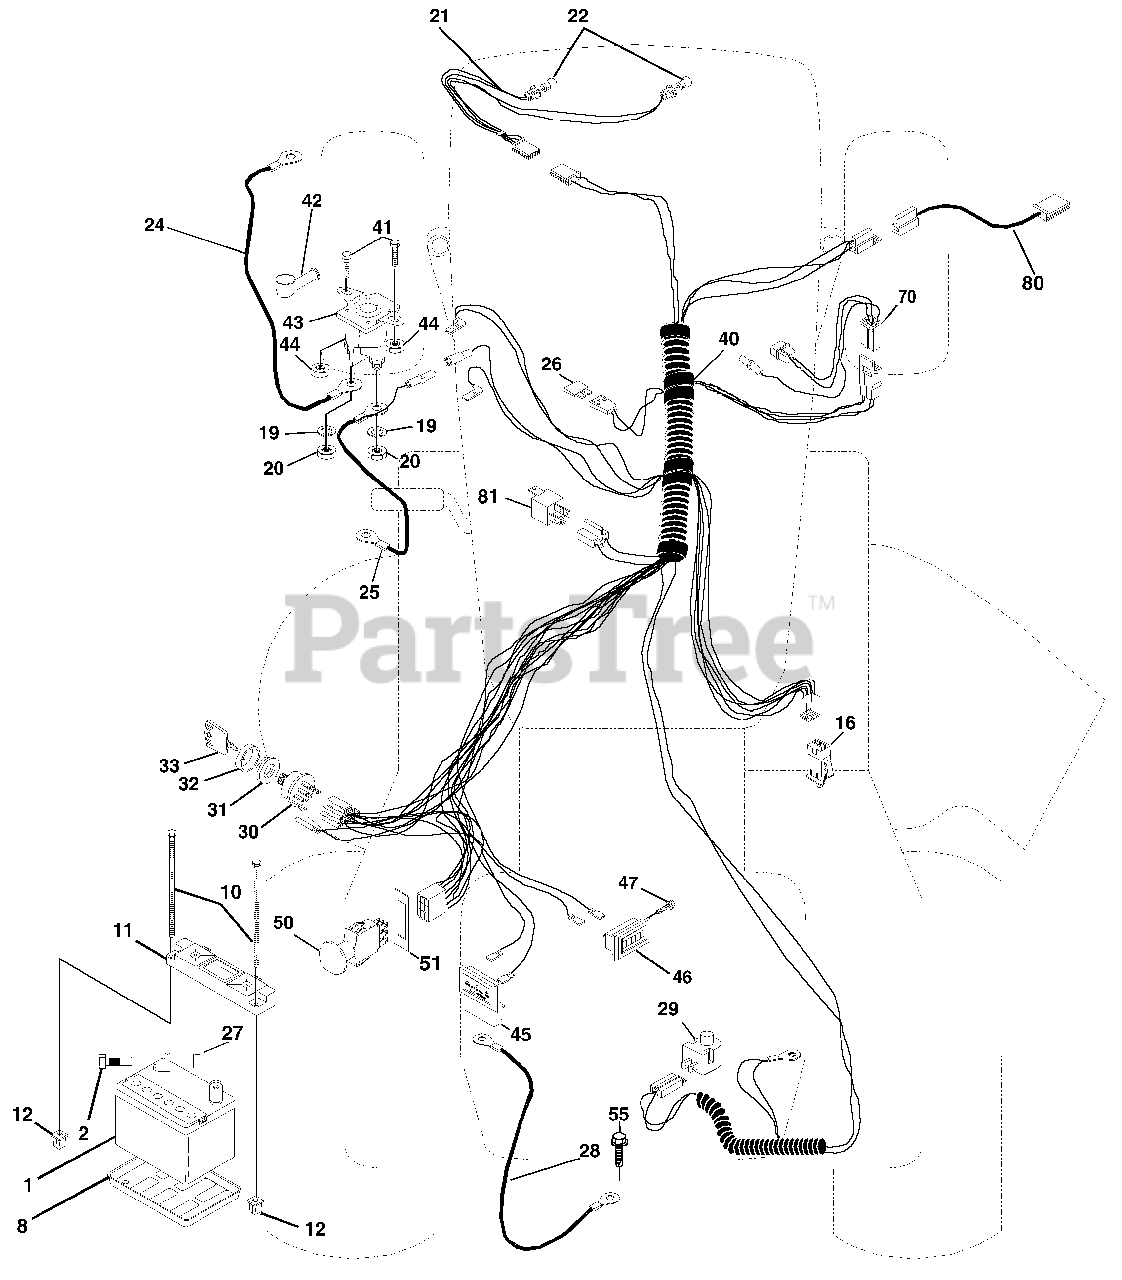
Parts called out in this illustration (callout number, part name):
1	Battery, 12 Volt, 35 Amp
2	Bolt, Hex Head 1/4-20 UNC x 3/4
8	Tray, Battery
10	Bolt, Battery Front 1/4-20 x 7.5 Zinc
11	Holddown Battery Dash Mount
12	Nut, Push Nylon 1/4" Battery Front
16	Switch Interlock Push-In
19	Washer, Lock 1/4
20	Nut, Jam, Hex Head 1/4-20 UNC
21	Harness, Light
22	Bulb, Light
24	Cable, Battery, 6 Gauge, 11", Red
25	Cable, Battery
26	Fuse, 15 Amp
27	Nut, Hex, Keps 1/4-20 UNC
28	Cable, Ground, 6 Gauge, 12", Black
29	Switch, Plunger, Normal Op Olive
30	Switch, Ignition, 4 Position
31	Nut, Ignition
32	Cover, Ignition Switch
33	Key, Ignition
40	Harness, Ignition
41	Bolt, Hex, Fin. 1/4-20 x 1/2
42	Cover, Terminal, Red
43	Solenoid
44	Nut, Hex, Keps 1/4-20 UNC
45	Ammeter, Rectangular, 15 AMP
46	Meter, Hour
47	Screw 10-24 x 1/2 Black
50	Switch, PTO
51	Ring, Retainer, PTO
55	Screw, Thdrol 5/16-18 x 1/2 TYT
70	Harness, Engine
80	Harness Clutch EVX
81	Relay Assembly
